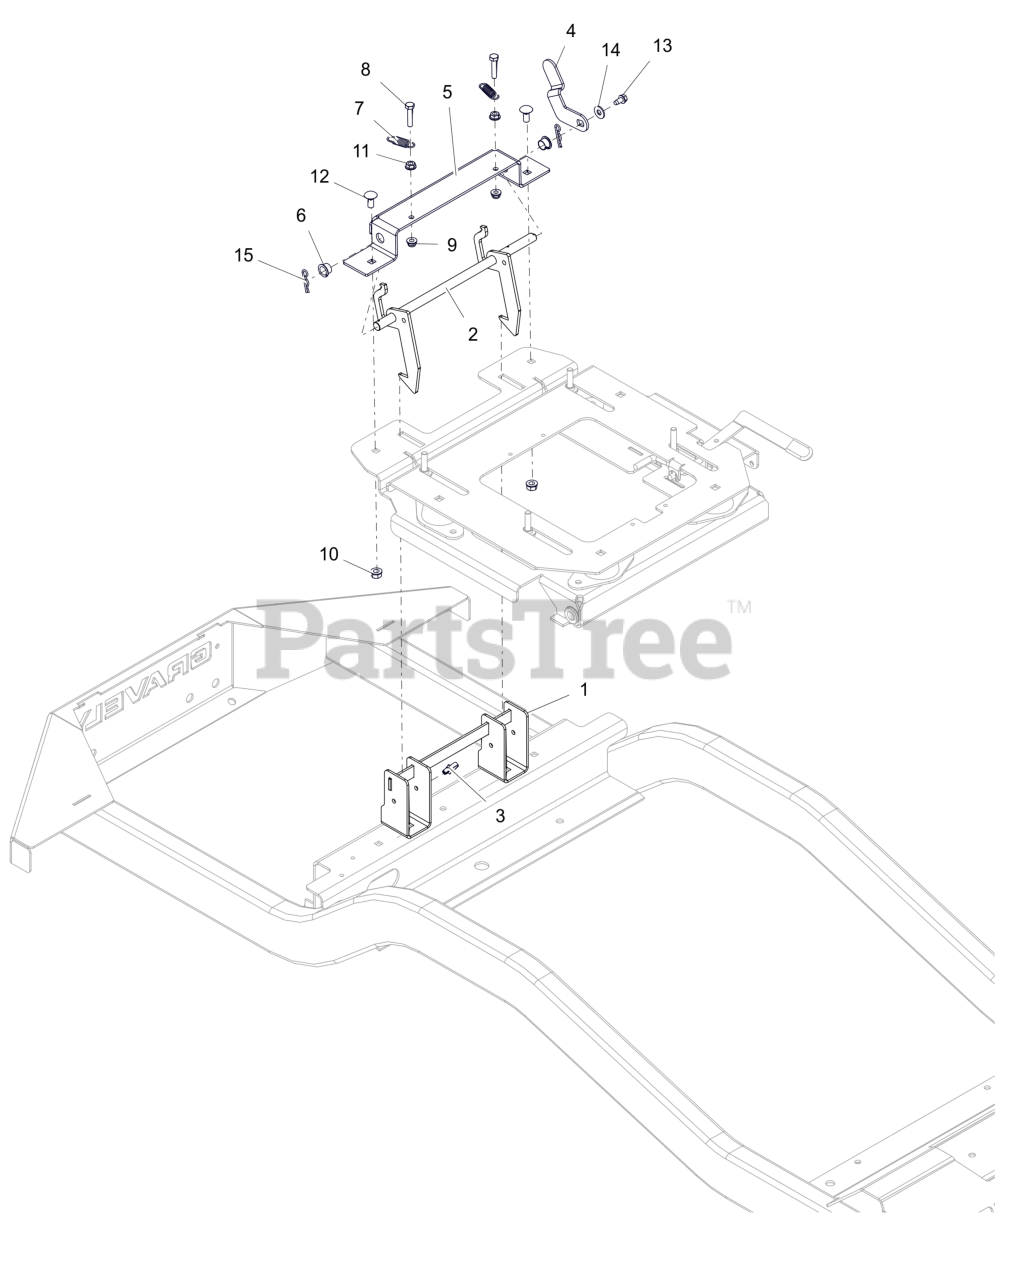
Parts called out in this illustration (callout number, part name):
1	WLDMT, LATCH RECEIVER
2	WLDMT, SEAT
3	ROUTING CLIP (1/2" ID)
4	LEVER, SEAT
5	BRKT, SEAT
6	BUSHING, POLYLINER-.50 SPLIT
7	SG-TENS .063X.44X1.56
8	BLT, HEX .25-20X1.25 G5 ZCC
9	NUT,NYL-FLG .25-20 GF ZCC
10	NUT,LK-CTR-FLG .31-18 GF ZCC
11	NUT-SPNLK-FLG .25-20 ZC120
12	BLT,RHSN .31-18X.75 G5 ZCC
13	SCR-TAP .25-20X.50 HWH ZCC
14	WSHR, FLT .312X.734X.065 ZCC
15	PIN, HAIR-INT .08X.38X1.42 ZCC
